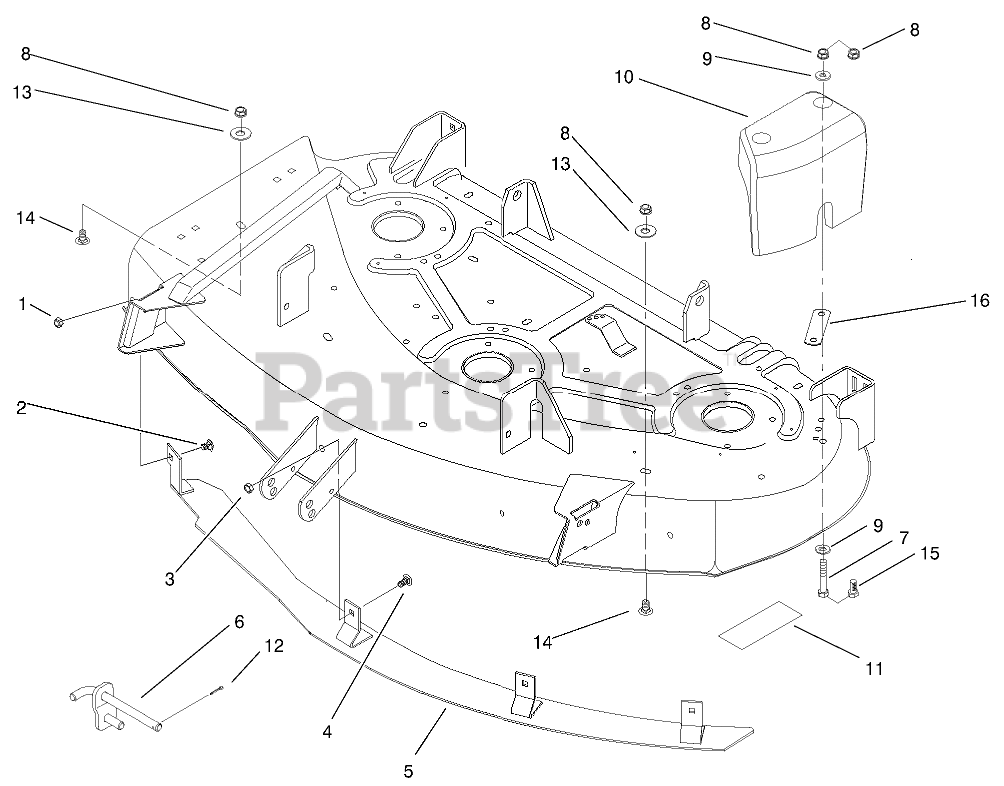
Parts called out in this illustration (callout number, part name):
1	NUT-LOCK, NI
2	SCREW-CARR
3	NUT-LOCK, NI
4	SCREW-CARR
6	ARM-LIFT, RH
7	SCREW-HH
8	NUT-LOCK, NI
9	WASHER-FLAT
10	WEIGHT-BAGGER, 44"
11	DECAL-DANGER
12	PIN-COTTER
13	WASHER-FLAT
14	SCREW-CARR
15	SCREW-HH
16	Cover
